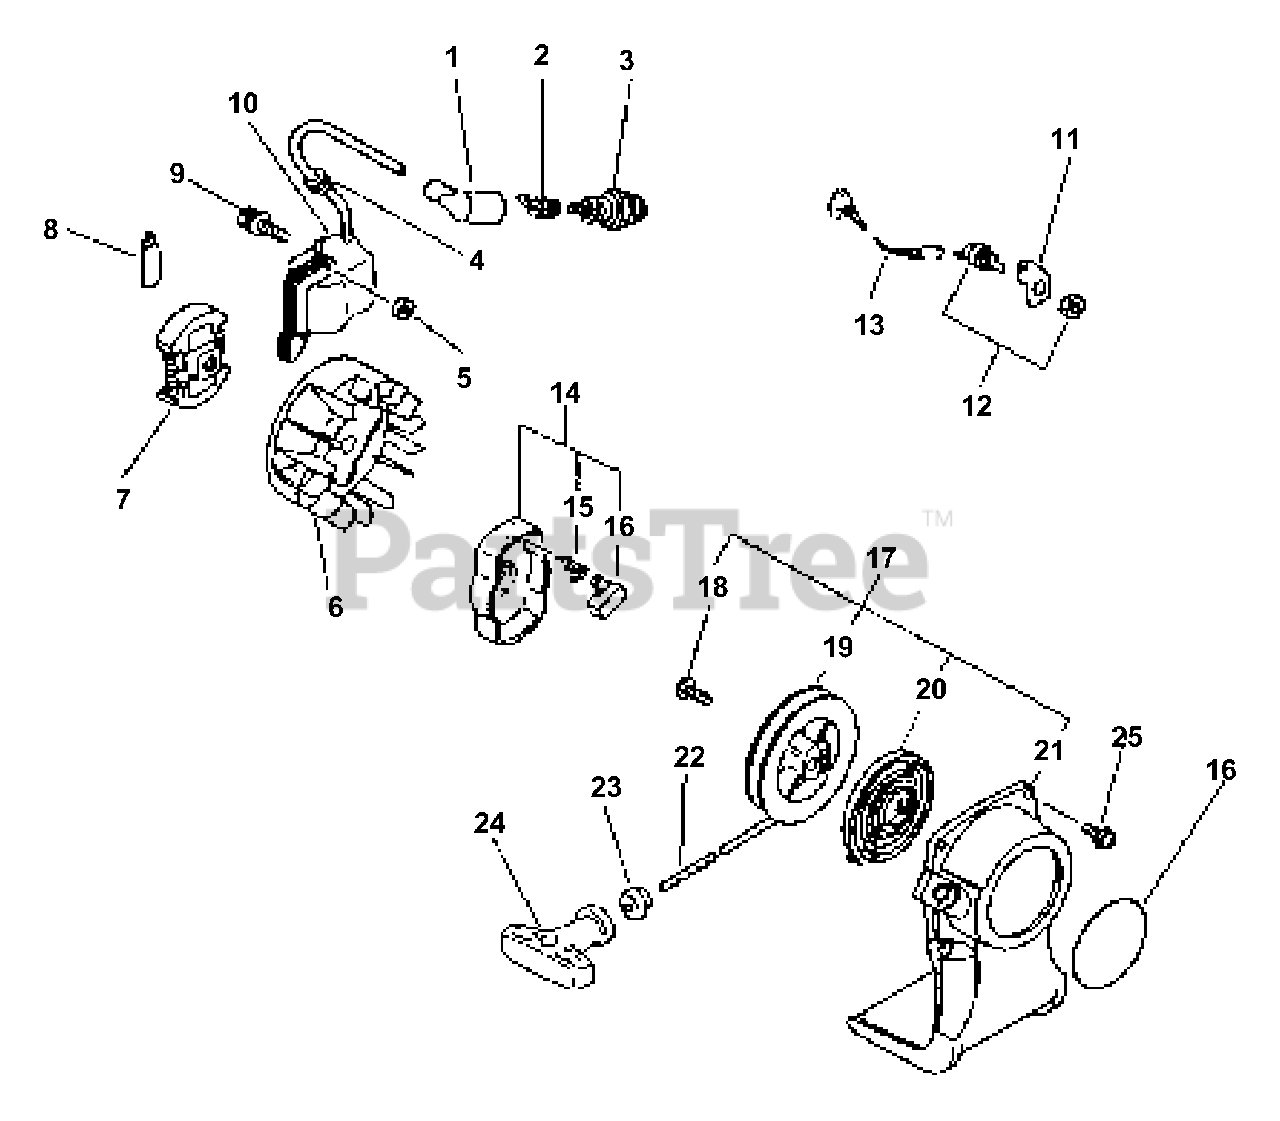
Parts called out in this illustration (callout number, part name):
1	CAP, SPARK PLUG
2	TERMINAL, SPARK PLUG CAP
3	SPARK PLUG -- BPM-7A
4	GROMMET
5	SPACER
6	FLYWHEEL
7	CLUTCH ASSY
9	SCREW - 4X22
10	COIL, IGNITION
11	BRACKET, SWITCH
12	IGNITION SWITCH ASSY
13	LEAD - GROUND
14	STARTER PAWL ASSY
15	SPRING, RETURN
16	PAWL, STARTER - BLACK
17	STARTER ASSY
19	REEL, ROPE
20	SPRING, REWIND
21	CASE, STARTER - BLUE
22	ROPE, STARTER - 3X1000
23	GUIDE, ROPE
24	GRIP, STARTER
25	SCREW - 4X16
26	LABEL - ECHO
